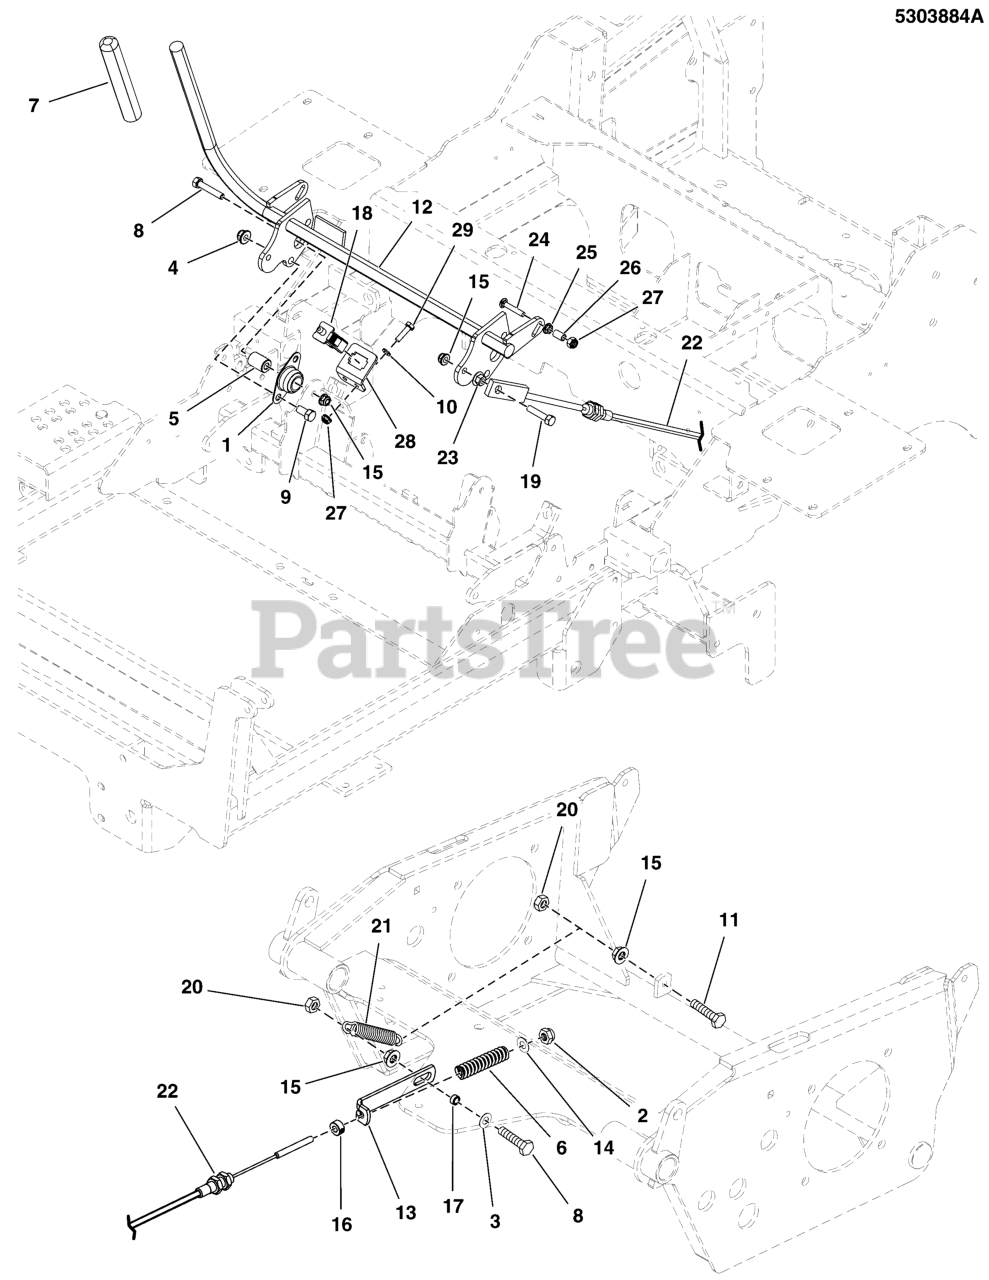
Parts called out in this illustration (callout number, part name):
1	BEARING, 3/4" FLANGED, BRONZE
2	NUT, 5/16-24 HEX NYLON LOCK
3	WASHER, 5/16" SAE
4	NUT, 3/8-16 HEX NYLOCK FLANGE
5	SPACER, .32 X .75 X 1.06, PM
6	SPRING, COMP. 1/2 ID X .140 WIRE X 3.25
7	GRIP, FOAM, 3/4 ID X 6 X .187
8	BOLT, 5/16-18 X 1-3/4 GD5 CZ
9	BOLT, 3/8-16 X 3/4" GD5 CZ
10	WASHER, 1/4 SAE
11	BOLT, 5/16-18 X 1-1/4 GD5 TFL, CZ
12	WELD, BRAKE SHAFT, LOCKOUT, 21" - BLK
13	LINK, BRAKE LOCK - BLK
14	WASHER, 5/16 USS
15	NUT, 5/16-18 HEX NYLOCK FLANGE
16	COLLAR, 5/16 SET
17	SPACER, .33 X .50 X .25, PM, CZ
18	SWITCH, DP NO/NC SNAP-IN
19	BOLT, 5/16-18 X 1-1/2 GD5 CZ
20	NUT, 5/16-18, HEX, CNTR LK,ZINC PHOS/OIL
21	SPRING, EXTENSION, .521 X 4.12, BLACK
22	CABLE, PARKING BRAKE, 32"
23	NUT, 5/16-18 HEX SERRATED FLANGE (LARGE)
24	BOLT, 1/4-20 X 1.500, GR5, SQ, ZINC/CLEA
25	NUT, 1/4-20 HEX SERR. FLANGE
26	SPACER, .25 X .38 X .63, CZ
27	NUT, 1/4-20 HEX NYLON LOCK
28	TAB, SWITCH PLATE, BOLT-ON - BLK
29	BOLT, 1/4-20 X 3/4 GD5 CZ
